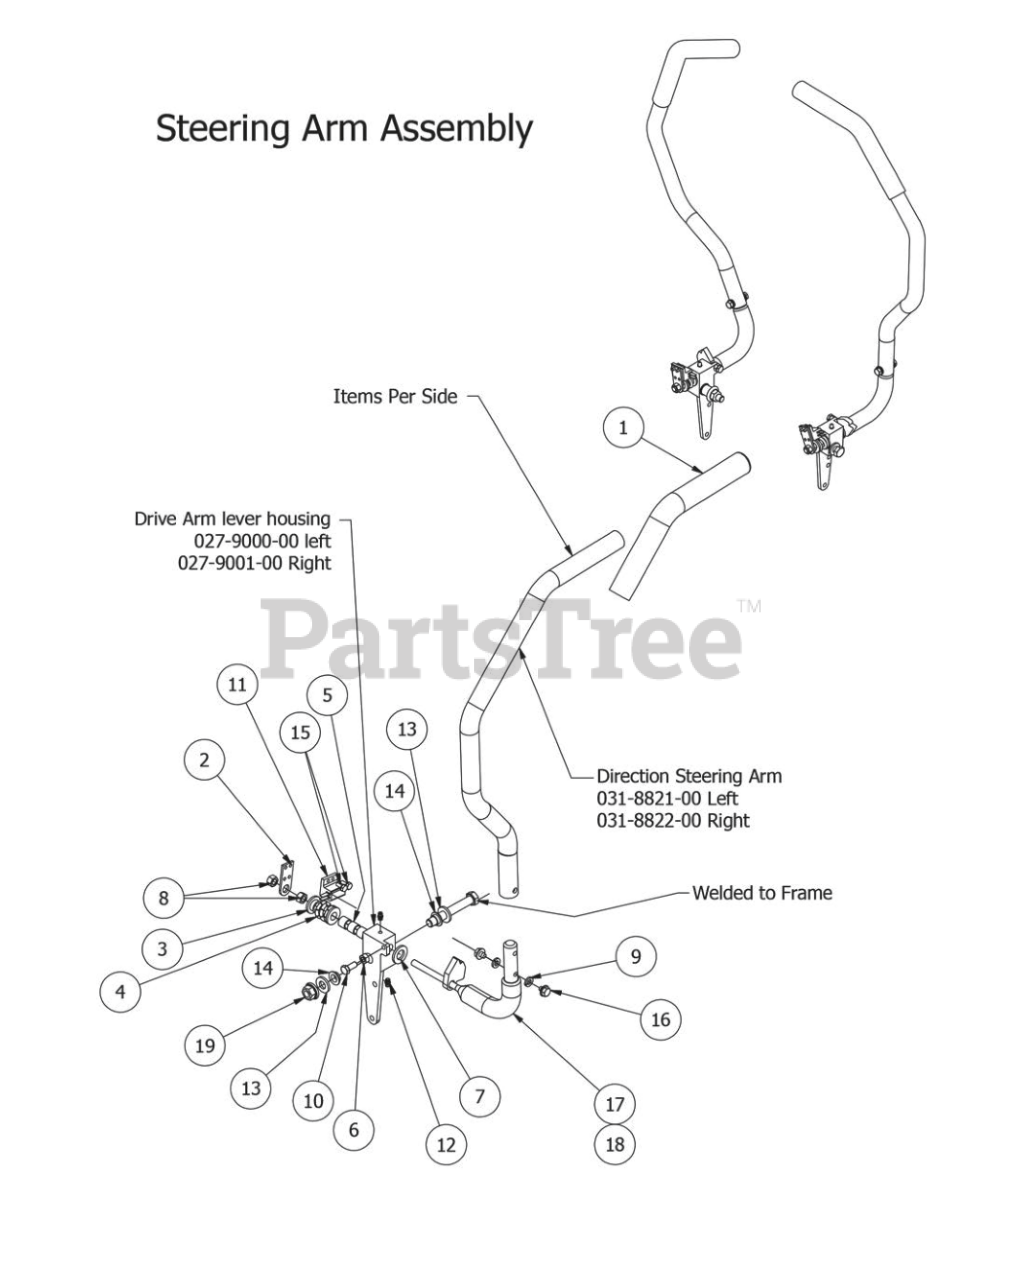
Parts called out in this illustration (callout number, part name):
1	Rubber Grip
2	MZ Switch Bracket
3	.515 ID Nylon Shoulder Washer
4	Drive Lever Spring
5	.507 ID Nylon Bushing
7	.635 ID Plastic Washer
8	3/8" Fine Threaded Jam Nut
9	5/16" Lock Washer
10	5/16" x 3/4" Hex Bolt
11	Safety Switch
12	1/4" Drive in Grease Fitting
13	.505x1x.125 Oil Impregnated washer
14	Bushing For 2012 Drive arm
15	12-24x 1/2 HWH Bolt
16	5/16-18 1/2 HWH Bolt-Steering
17	Steering Arm Elbow (Right)
18	Steering Arm Elbow (Left)
19	1/2-13 Hex Flange (GR.G) ZC
